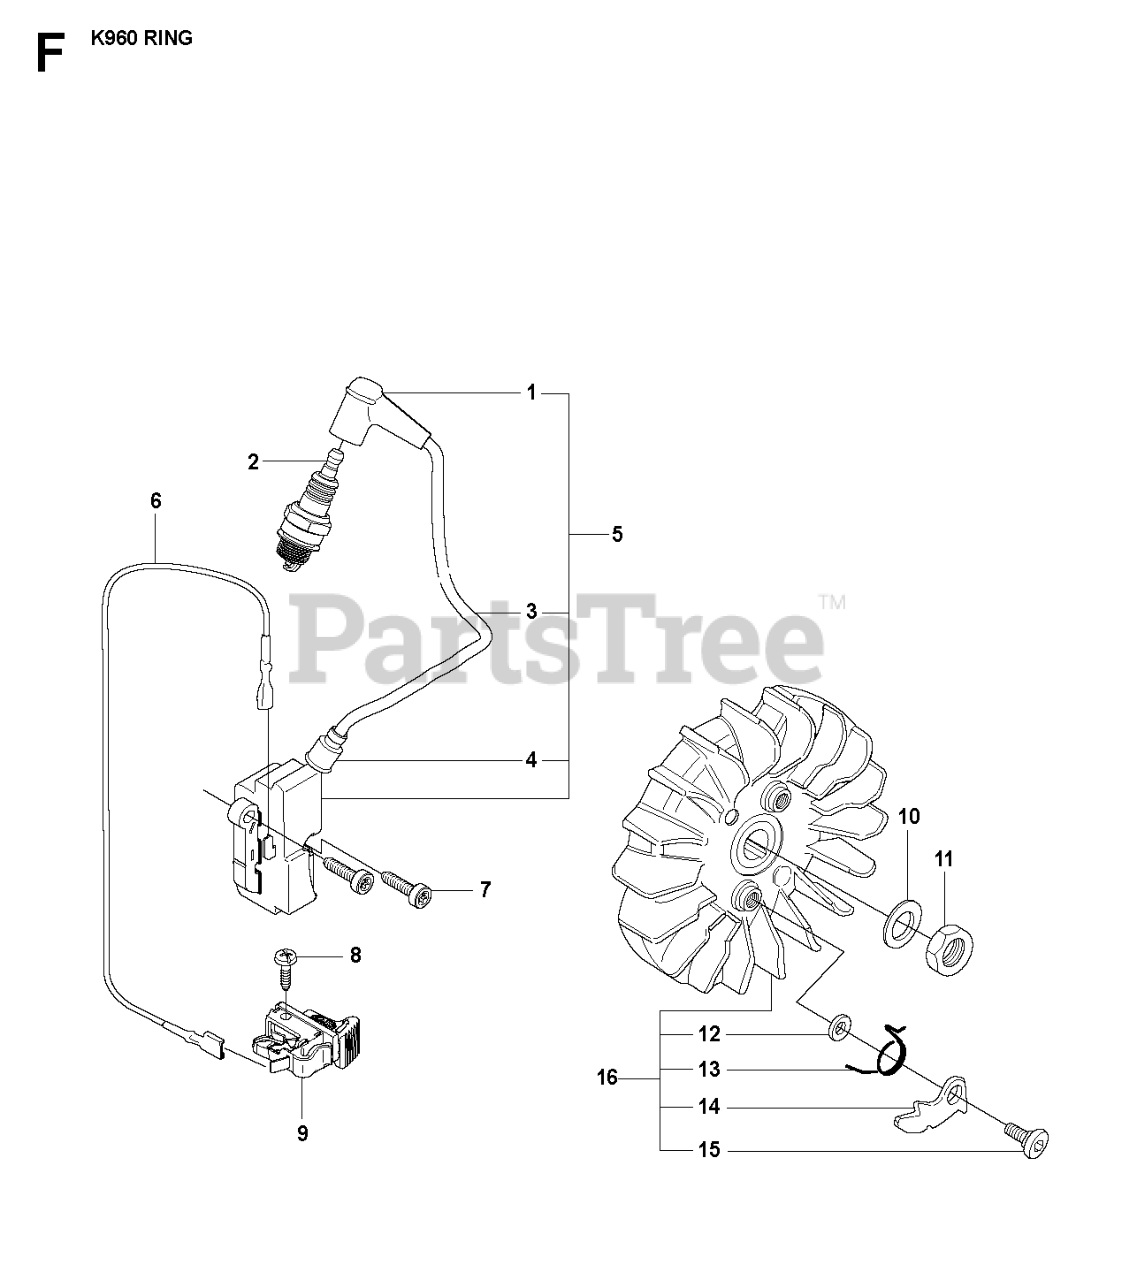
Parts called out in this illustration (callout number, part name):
1	SPARK PLUG CONN. KIT
2	SPARK PLUG RCJ6Y NLA
3	CABLE STOP SWITCH
4	INSULATING CAP
5	%IGNITION MODULE
6	SHORTING LEAD
9	STOP SWITCH
10	WASHER 8.4X16
15	SCREW M5X14
